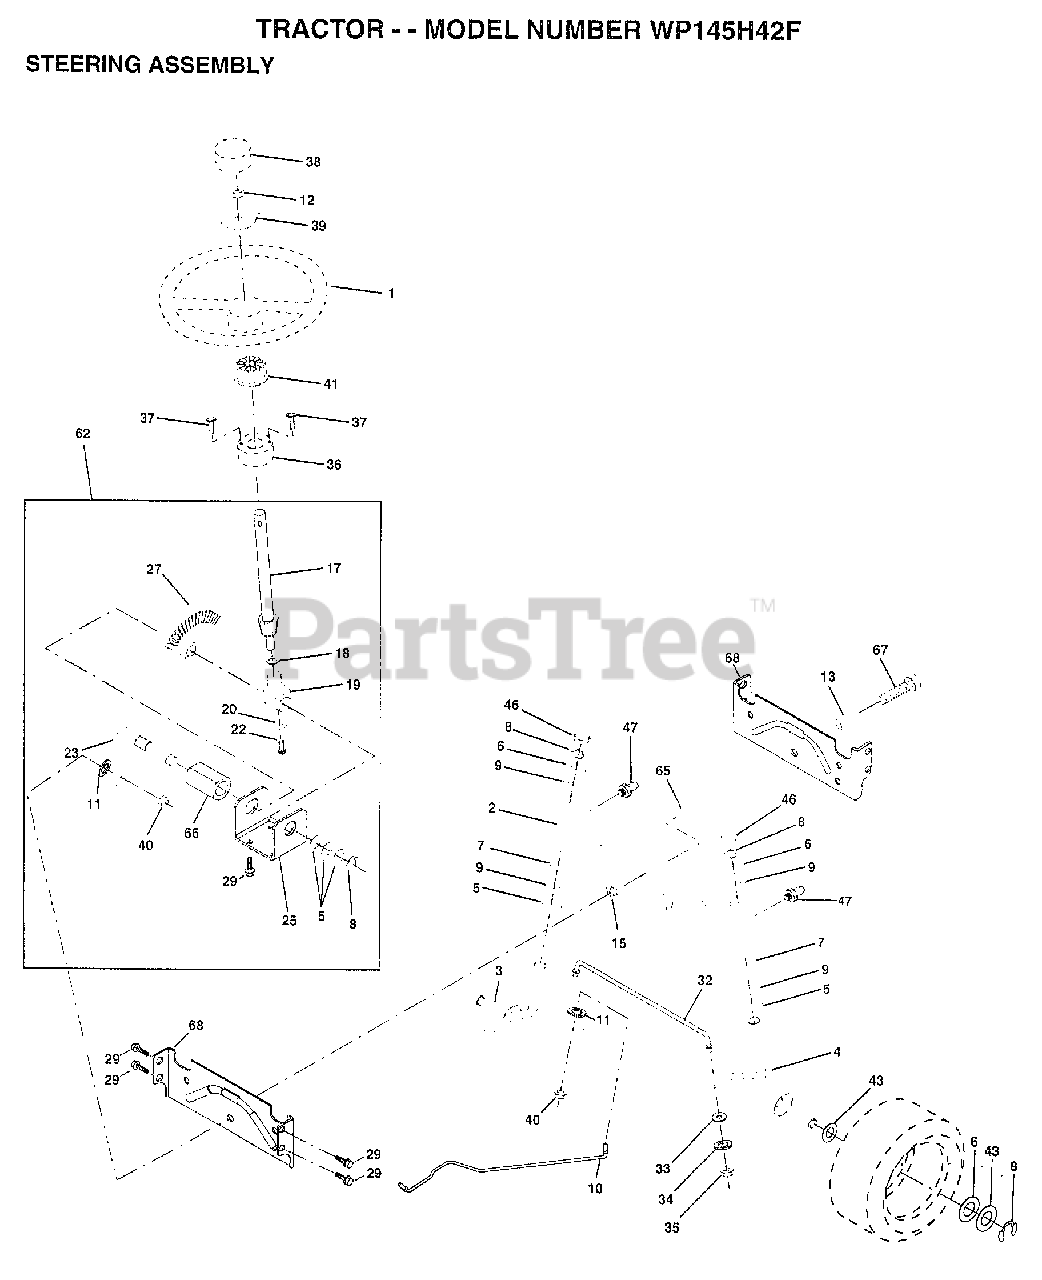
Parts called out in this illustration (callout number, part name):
2	AXLE ASM
3	SPINDLE.ASM.LH
4	"SPINDLE ASM,RH"
5	WASHER .T
6	WASHER
7	WASHER
8	RING
9	COL. SRTG. BEAR.
10	DRAGLINK-STAMPED
11	LOCKWASHER
13	BEARING AXLE
15	"NUT-LOC,FLANGE LT"
17	SHAFT ASM STEERNG
18	THRUST WASHER
19	SUPPORT.SHAFT
22	SCREW HEX SOC1/4-
25	BRKT-STEERING
27	GEAR SECTOR
29	SCREW
32	ROD.TIE.19.75
33	WASHER M
34	LOCKWASHER
35	NUT.LOCK.5/16-24
36	BUSHING.STRG.3/4
37	"SCREW-TT,10-32 FL"
38	"INSERT,STR WHEEL"
39	WASHER
40	GRIPCO NUT
41	ADAPTER LT
46	CAP
47	ZERK M
62	KIT STEERING ASM
65	SPACER AXLE
66	"BEARING-ARM,PITMA"
67	BOLT
68	BRACE AXLE
